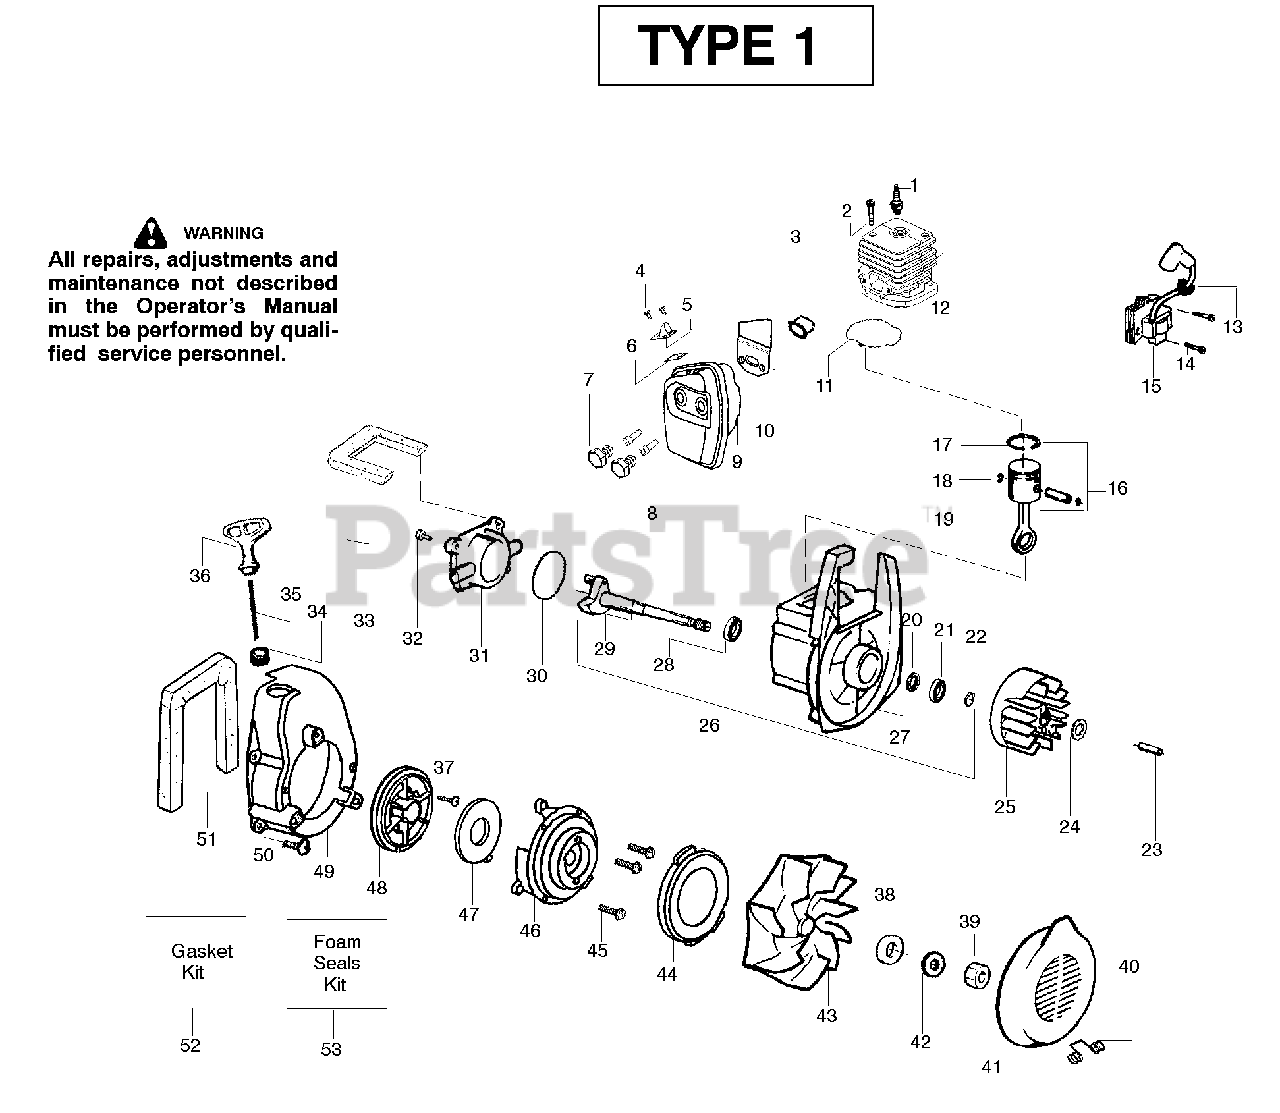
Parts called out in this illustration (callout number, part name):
1	Spark Plug (RCJ-8Y)
3	Insulator-Heat
5	Deflector-Muffler
6	Kit-Spark Screen
7	Bolt-Muffler-external
8	Screw-Muffler-Internal
9	Kit-Muffler
10	Gasket-Baffle (kit)
11	Gasket-Cylinder (kit)
12	Kit-Cylinder
13	Grommet-Ign. Module
14	Screw-Ignition Module
15	Ignition Module
16	Kit-Piston
17	Piston Ring
18	Retainer-Piston Pin
19	Assy-Connecting Rod
20	Seal-Crankcase
21	Bearing-Outer
22	Retainer Ring-C'shaft
23	Spacer-Flywheel
25	Assy-Flywheel
26	Assy-Crankcase/Crank shaft
27	Assy-Crankcase
28	Bearing-Inner
29	Assy-Crankshaft
30	O-ring-C/case (kit)
31	Cover-Crankcase
32	Screw
33	Foam-219mm (kit)
34	Eyelet-Flange
35	Kit-Rope
36	Handle-Starter
37	Screw-Rope
38	Washer-Flat
40	Spring-Return Cover
41	Inlet Door
42	Washer-Belleville
43	Assy-Impeller
44	Seal-Ring
46	Housing-Pulley
47	Spring-Starter
48	Kit-Starter Pulley
49	Fan Housing
50	Screw
51	Foam-365mm (kit)
52	Kit-Gasket
53	Kit-Foam Seals
